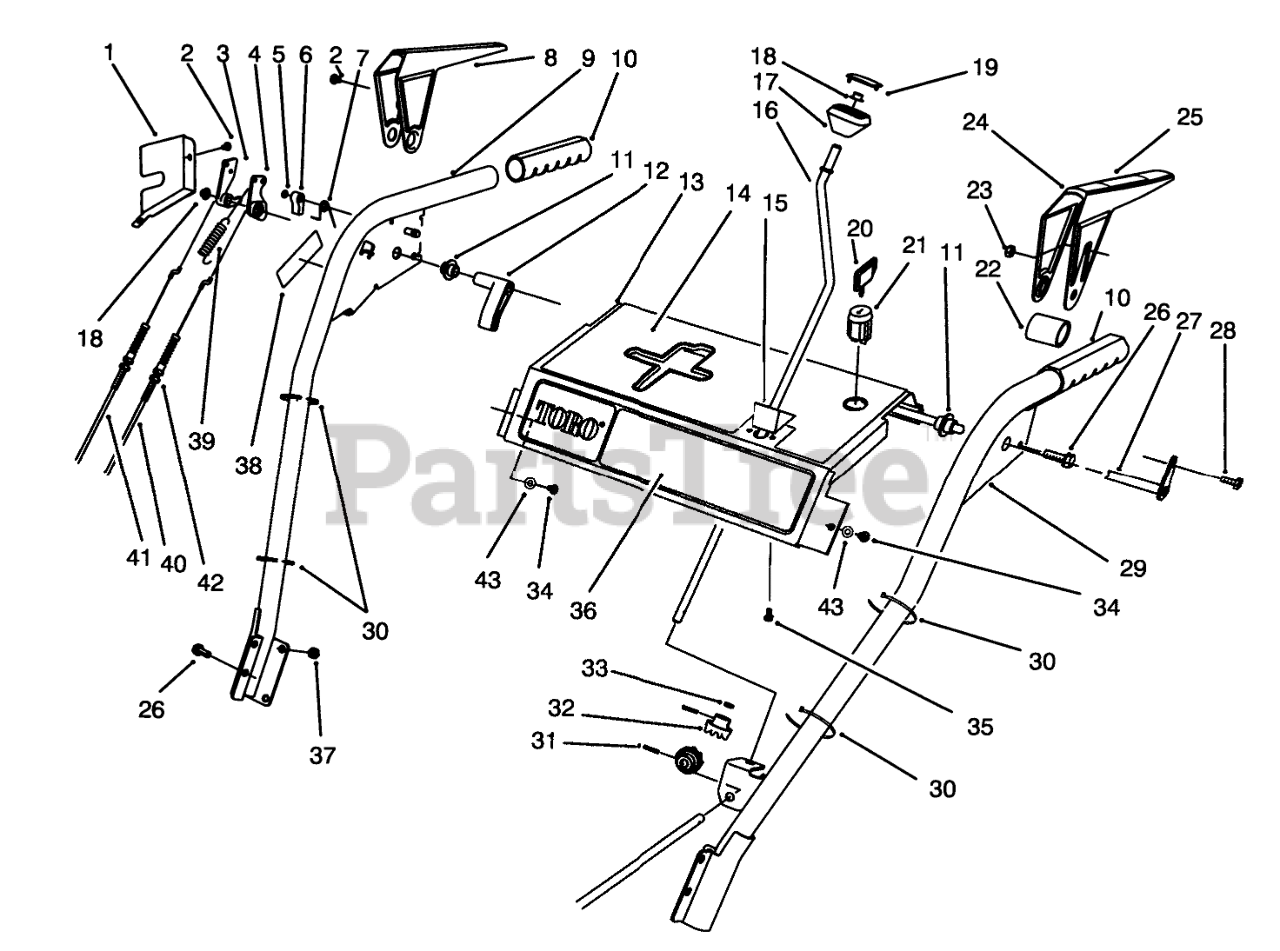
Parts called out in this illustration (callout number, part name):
1	Cover Lever Lock
2	SCREW-HH
3	TANG-LOCKING
4	CAM-RELEASE
5	E-RING-RETAINER
6	LATCH-LOCKING
7	SPRING-TORSION
8	Lever-Impeller
9	Handle-R.H.
10	GRIP-HANDLE
11	BUSHING-LEVER
12	LEVER-TRIP
13	Panel-Control
14	DECAL-TOP PANEL
15	PLATE-GUIDE
16	CRANK-ROD, CHUTE
17	KNOB-CONTROL, CHUTE
18	RETAINER-PUSH ON
19	COVER-KNOB
20	KEY-IGNITION
21	SWITCH
22	SPACER-LEVER, TRACTION
23	NUT-LOCK, NI
24	Lever-Traction
25	DECAL-LEVER
26	SCREW-HHF
27	CROSS ROD ASM
28	SCREW-HWH
29	Handle-L.H.
30	TIE-CABLE
31	PIN-SPRING
32	GEAR-UNIVERSAL
33	WASHER-RUBBER
34	SCREW-HWHTF
35	SCREW-PPH
36	DECAL-FRONT PANEL (828)
37	NUT-LOCK, NI
38	DECAL-WARNING
39	SPRING-EXTENSION
40	CABLE-TRACTION
41	CABLE-IMPELLER
42	NUT-LOCK, NI
43	WASHER-FLAT
